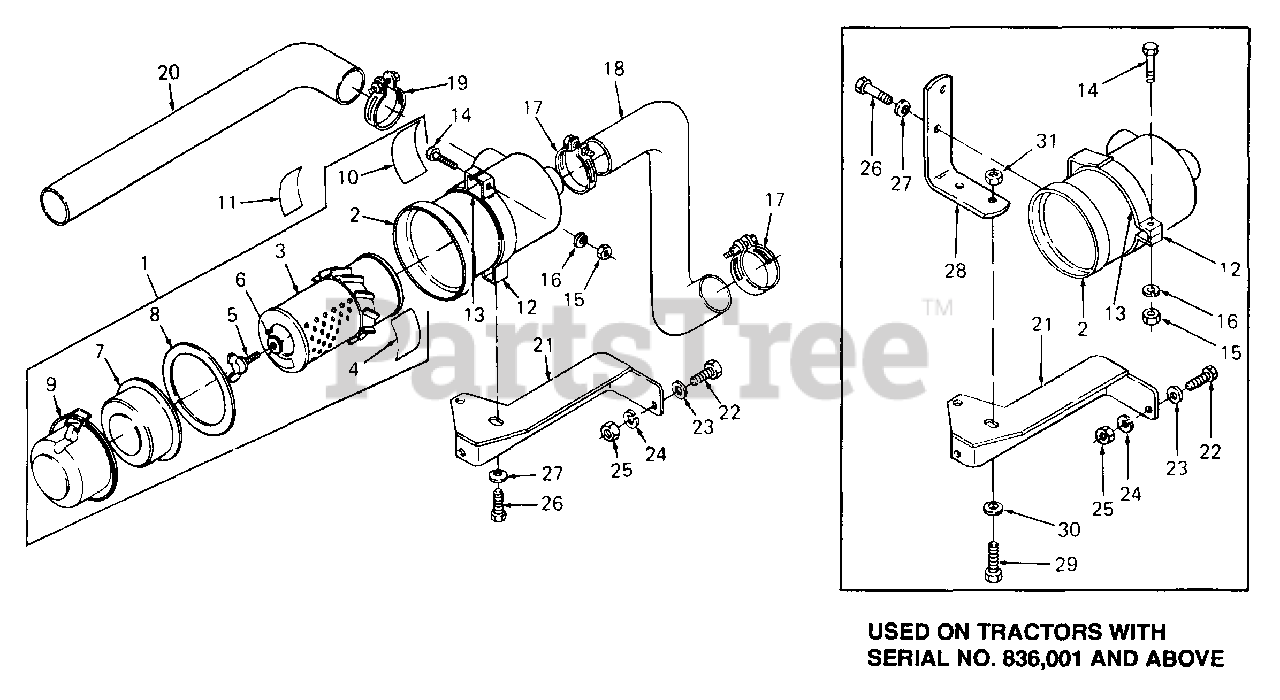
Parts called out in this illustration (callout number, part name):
1	Air Cleaner Assy
2	Body, Air Cleaner
3	Element, Air Cleaner
4	Label, Air Cleaner Element
6	Washer w/Rubber
7	Cover, Baffle
8	Gasket, Air Cleaner Cover
9	Cover, Air Cleaner
10	Label, Air Cleaner
11	Label, Ether Caution
12	Band, Air Cleaner
16	Washer, Spring
17	Clamp, Hose
18	Hose, Diesel Air Inlet
19	Clamp, Hose
20	Hose, Air Intake
21	Bracket, Air Cleaner Mtg
22	Screw, Hex Cap, 5/16-18 X .75 Lg GR5
23	Washer, Flat, .344 X 1.5 X .105 Thk
24	Washer, Lock, 5/16
25	Nut, Hex, 5/16-18 GR5
26	Screw, Hex Cap, M8-1.25 X 20 mm GR5
27	Washer, Bell, .345 X .88 X .060 Thk
28	Bracket, Air Cleaner
29	Screw, Hex Cap, 5/16 x 18 x .50 Lg GR5
30	Washer, Bell, .345 x .88 x .060 Thk
31	Nut, Hex Center Lock, 5/16-18 GR5
